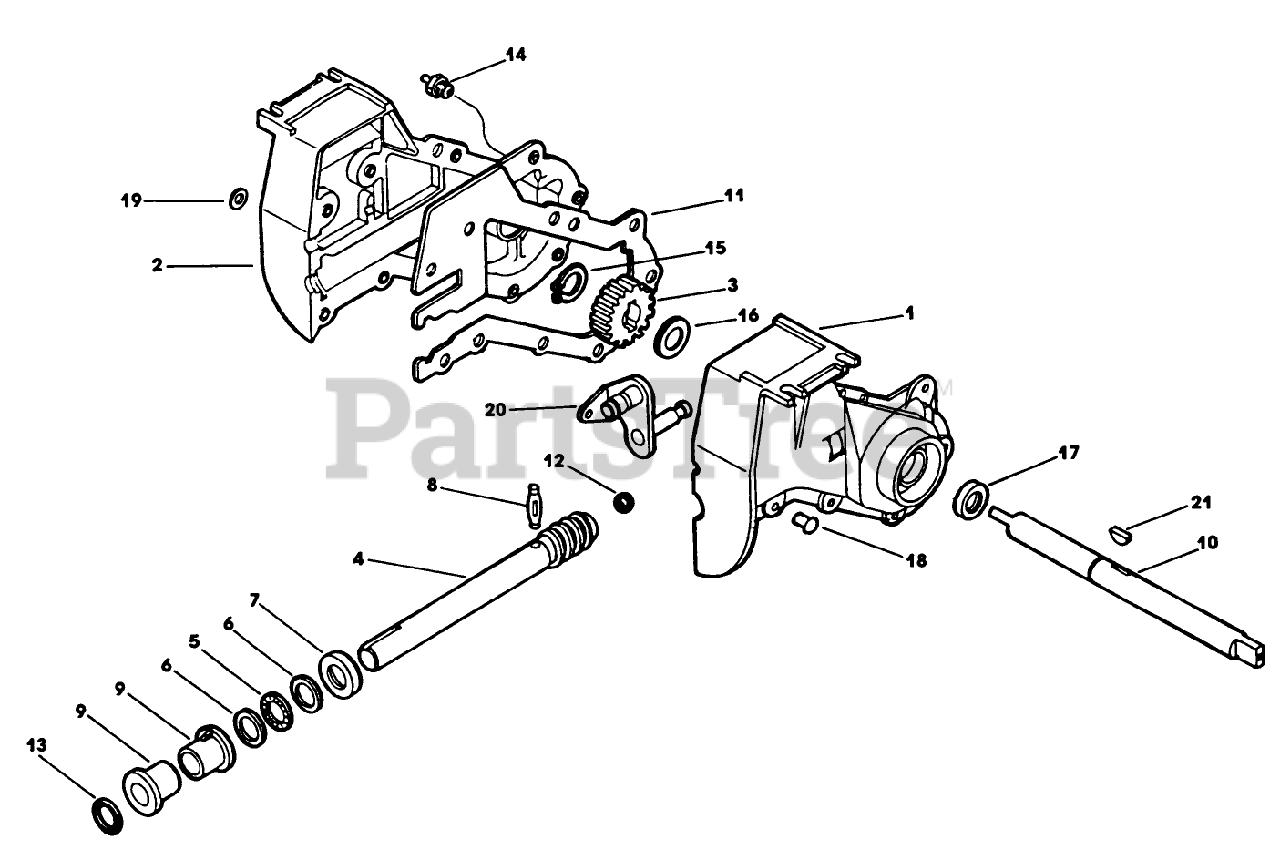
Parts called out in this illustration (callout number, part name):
4	SHAFT-WORM
7	WASHER
10	SHAFT
11	GASKET
13	O-RING
15	RING-RETAINING
16	WASHER
17	SEAL
18	RIVET
20	IDLER ARM ASSY
